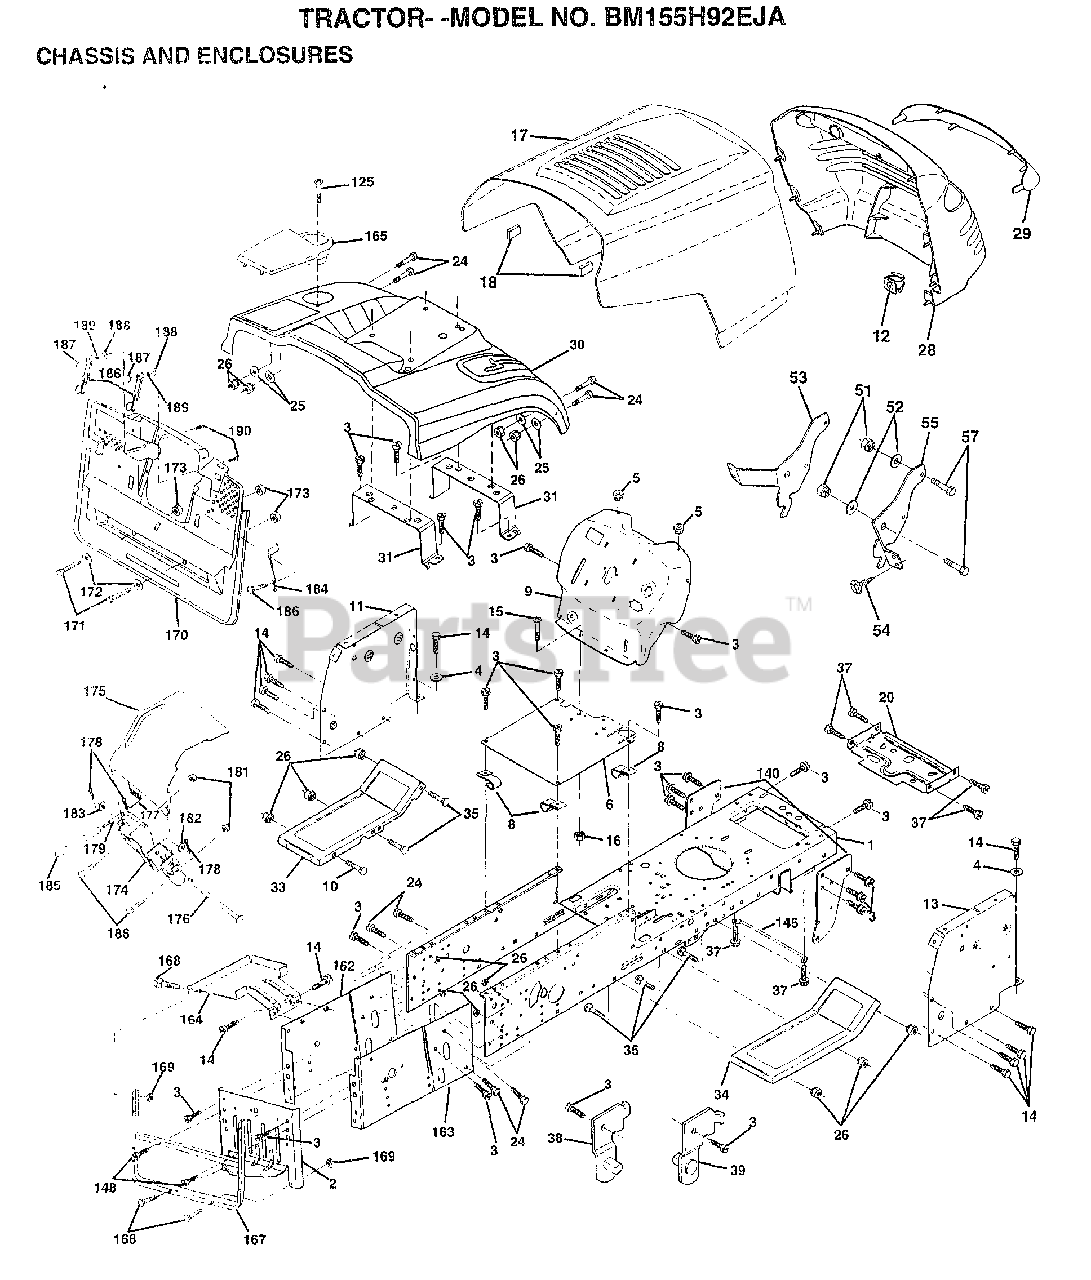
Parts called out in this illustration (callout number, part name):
1	CHASSIS.STAMPING
2	DRAWBAR.CRD
3	SCREW
4	WASHER
5	BUMPER-HOOD/DASH
6	SADDLE
8	"CLIP,INSULATOR"
9	DASH.PANEL.ASSY
11	"PANEL-DASH,LH"
12	CLIP.TINNERMAN
14	SCREW LT
15	SCREW
17	HOOD.PNT.W/TRIM
20	"PLATE-MTG,BATT/FU"
24	BOLT
25	WASHER
26	NUT
28	GRILLE-MS428
29	LENS.GRILLE.PRIVATE LABEL
30	FENDER.AUTO.POLO.MS558
31	BRKT.SUPT.FENDER.CRD
33	FOOTREST.LH.YT/GT
34	FOOTREST.RH.LT/YT
35	BOLT
37	SCREW LT
38	BRACKET ASM LH
39	BRACKET ASM RH
51	NUT
52	WASHER
53	BRACKET.GRILLE.LH
54	SCREW.HEX.WS.HD
55	BRACKET.GRILLE.RH
58	AIR DUCT
125	SCREW
140	BRKT SUSPENSION
145	"ROD POVOT,CHASSIS"
148	SCREW
162	BRKT.EXT.CHASSIS.LH.CRD
163	BRKT.EXT.CHASSIS.RH.CRD
164	SUPPORT.BATTERY.CRD
165	COVER.BATTERY.CRD.BLACK.LT
167	SUPT.ASM.BACKPLATE
168	BOLT-RD HD SQ NK
170	COVER.BACKPLATE.BLACK
171	BOLT
173	NUT
174	BRKT.SWITCH.FBI.CRD
175	GRUARD.DOOR.REAR.CRD
176	HINGE PIN
177	SPRING.COVER.LH
179	ROD.PIVOT.FBI.CRD
182	WASHER.385X.625
183	WASHER
184	BRKT.ACTUATOR.BAG.CRD
185	TUBE.LEVER.SWCH.FBI.CRD
